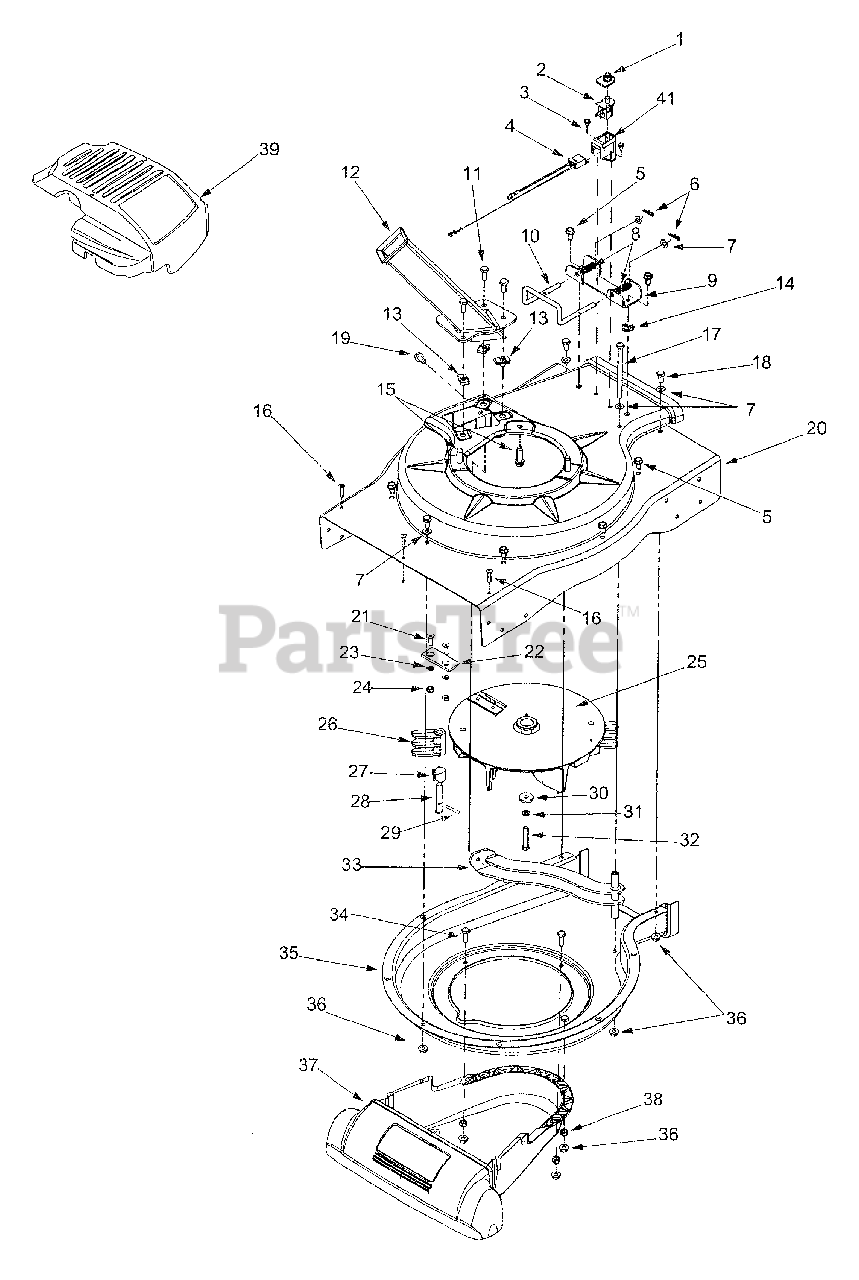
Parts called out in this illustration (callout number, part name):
1	Switch Cover
2	Safety Switch
3	Hex Washer Screw #10-16 x .50
4	Wire Harness
5	Hex Washer Screw 5/16-18 x .625
6	Cotter Pin
7	Flat Washer .330 ID x .630 OD
8	Compression Spring
11	Hex Cap Screw 5/16-18 x .75
13	U-Clip Lock Nut 5/16-18
14	External Lock Washer 5/16
15	Hex Washer Screw 3/8-16 x 1.25
16	Screw #12-16 x 1.0
17	Hex Cap Screw 5/16-18 x 4.5
18	Hex Cap Screw 5/16-18 x .625
19	Hex Washer Screw 5/16-18 x .625
22	Chipper Blade
23	Lock Washer 5/16
24	Hex Lock Nut 5/16-24
25	Impeller Assembly
26	Flail Blade
28	Clevis Pin
29	Spiral Pin
30	Flat Washer .375 ID x 1.25 OD
31	Lock Washer 3/8
32	Hex Cap Screw 3/8-24 x 2.0
34	Hex Cap Screw 5/16-18 x .875
36	Lock Nut 5/16-18
37	Nozzle Cover
38	Lock Nut 5/16-18
41	Safety Switch Cover
